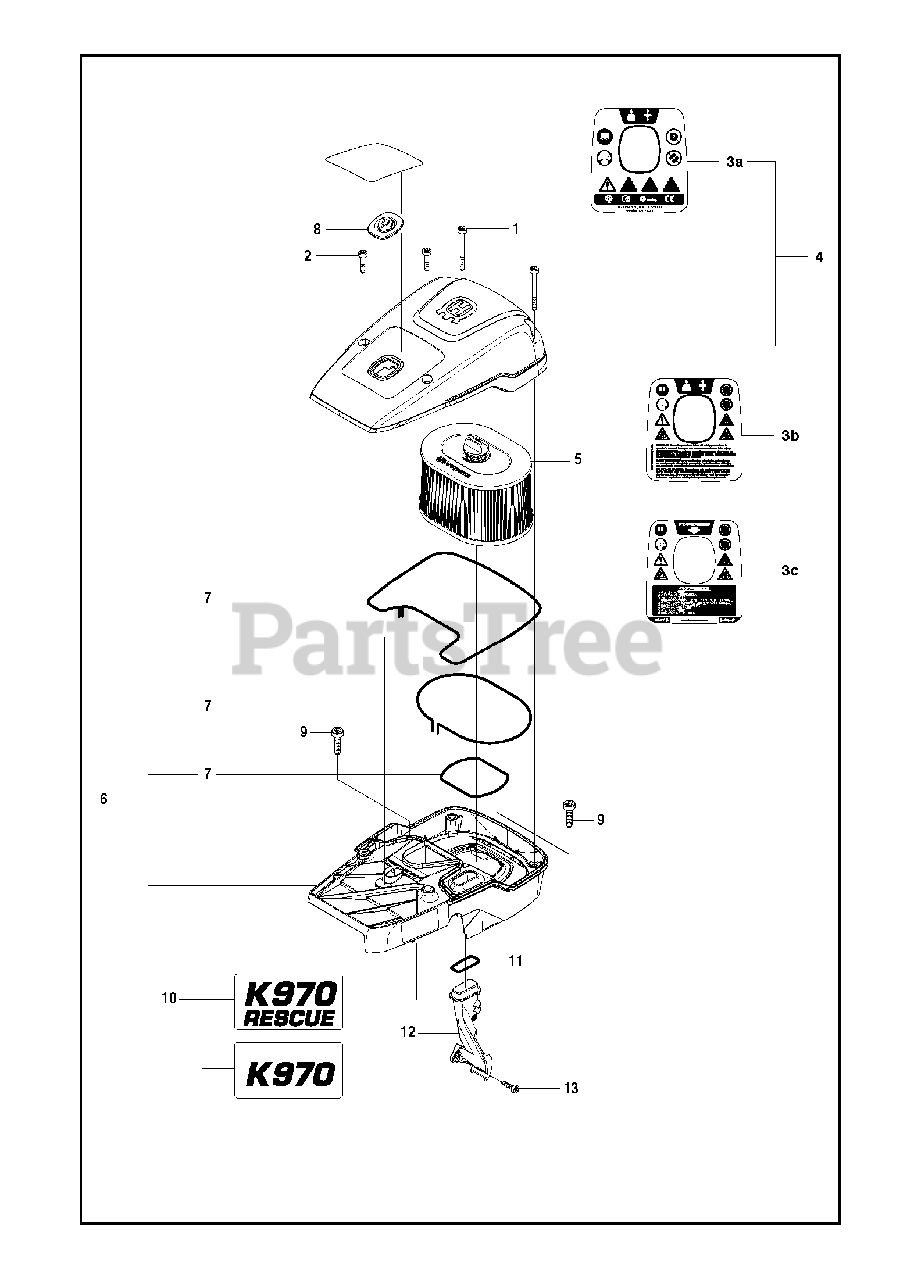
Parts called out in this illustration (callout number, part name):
1	SCREW ITXSCM
2	SCREW ITXSCM
4	FILTER COVER ASSY
5	AIR FILTER
6	CYLINDER COVER ASSY
9	SCREW ITXSCM
13	SCREW ITXSCM
